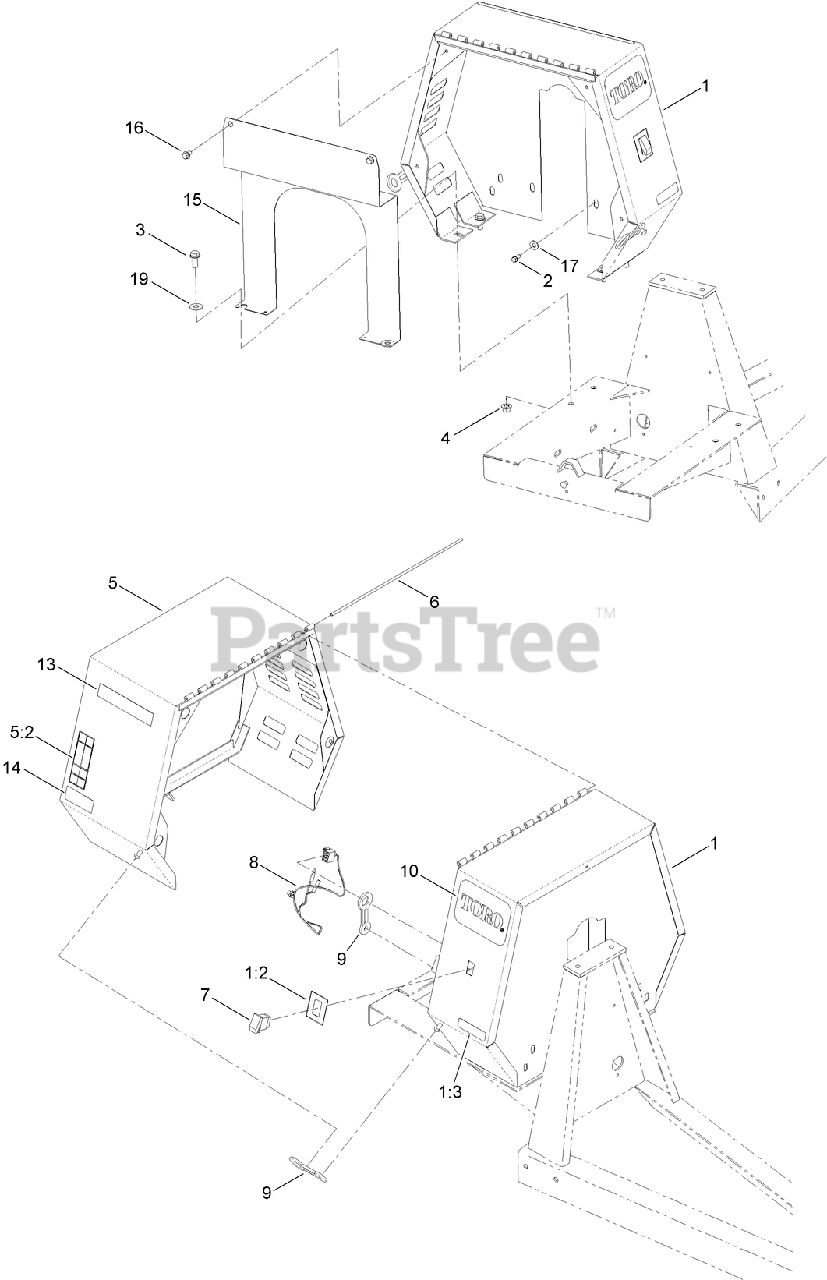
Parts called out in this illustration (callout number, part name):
1	STATIONARY COWL ASM
1:2	DECAL-STOP, ENGINE
1:3	DECAL-ARRESTER, SPARK
2	SCREW-HWHTF
3	SCREW-HHF
4	NUT-LOCK
5	MOVABLE COWL ASM
5:2	DECAL-WARNING
7	SWITCH
8	HARNESS-WIRE, MIXER
9	LATCH-RUBBER
10	DECAL
15	PLATE-ENGINE
16	SCREW-HWH
17	WASHER-FLAT
19	WASHER-FLAT
